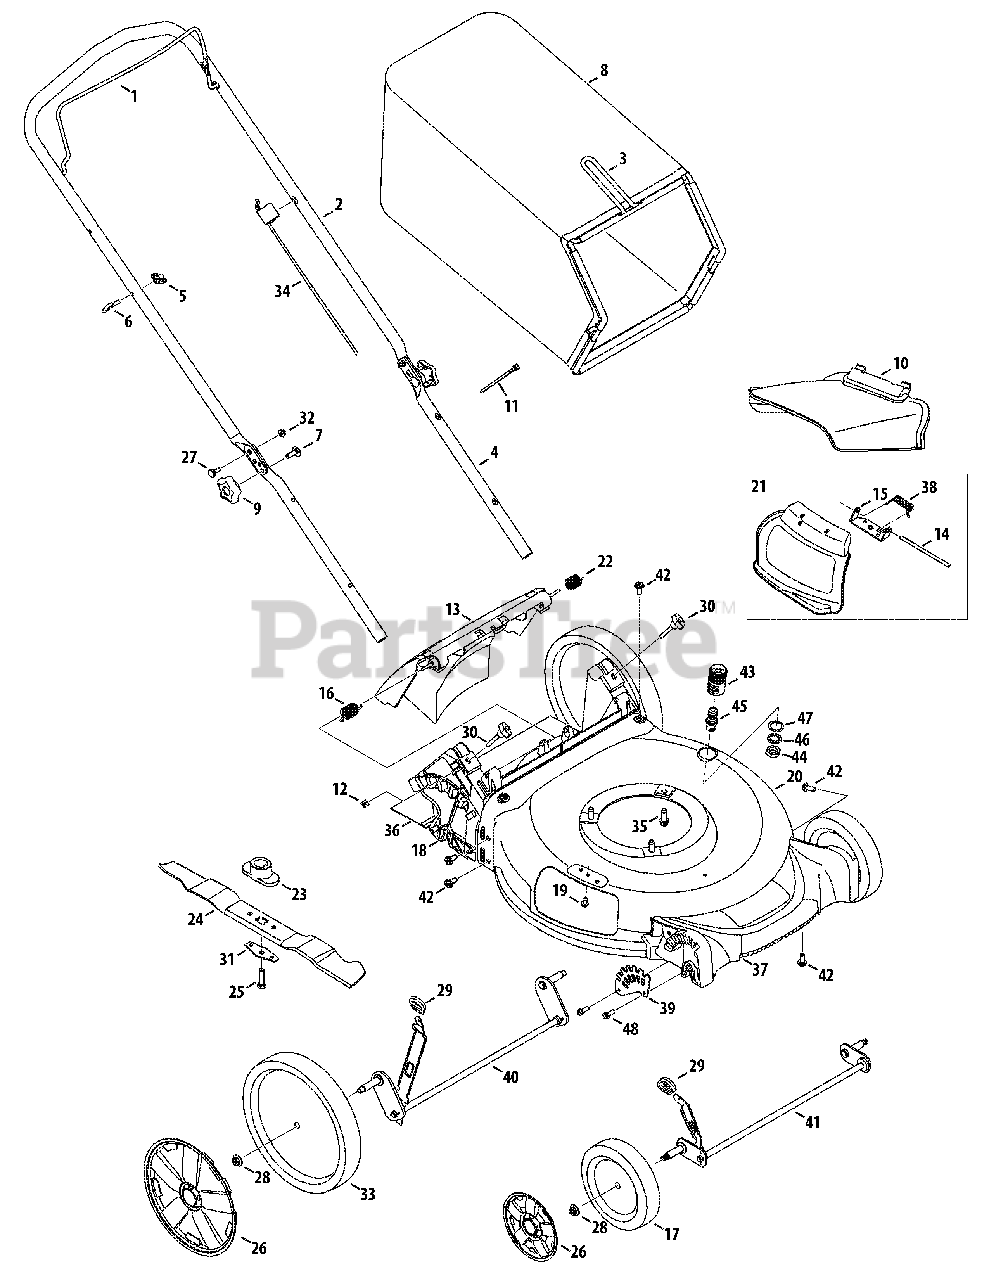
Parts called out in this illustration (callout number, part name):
1	Blade Control
2	Upper Handle
3	Grass Catcher Frame
4	Lower Handle
5	Wing Nut
6	Rope Guide
7	Carriage Screw ,5/16-18
8	Grass Bag
9	Hand Knob
10	Side Chute
11	Cable Tie
12	Nut, Sq., 1/4-20
13	Rear Discharge Door
14	Hinge Pin
15	Chute Deflector Bracket
16	Torsion Spring - RH
17	Wheel, 7 x 2
18	Rear Baffle
19	Screw, 1/4-20 x .500
20	Deck - 21"
21	Hinged Mulch Plug Assembly
22	Torsion Spring - LH
23	Blade Adapter
24	Mulching Blade
25	Screw , 3/8-24 x 1.50
26	Hub Cap - Front
26	Hub Cap - Rear
27	Sldr. Screw, .375 x .126 x 1/4-20
28	Flange Lock Nut, 3/8-16
29	Adjustment Lever Knob
30	Wing Nut
31	Blade Bell Support
32	Nut, Flange Lock, 1/4-20
33	Wheel, 11 x 2
34	Control Cable
35	TT Sems Screw, 3/8-16 x 1.0
36	Trail shield
37	Front Cover
38	Torsion Spring
39	Front Height Adjuster Plate
40	Rear Axle Assembly
41	Front Axle Assembly
42	Screw, 5/16-14 x .750
43	Water Nozzle
44	Nut, Hex, M16-1.5
45	Water Nozzle Adapter
46	Washer, Lock, 5/8
47	Washer, Flat, .865 x 1.145 x .030
48	Screw, 1/4-15 x .750
